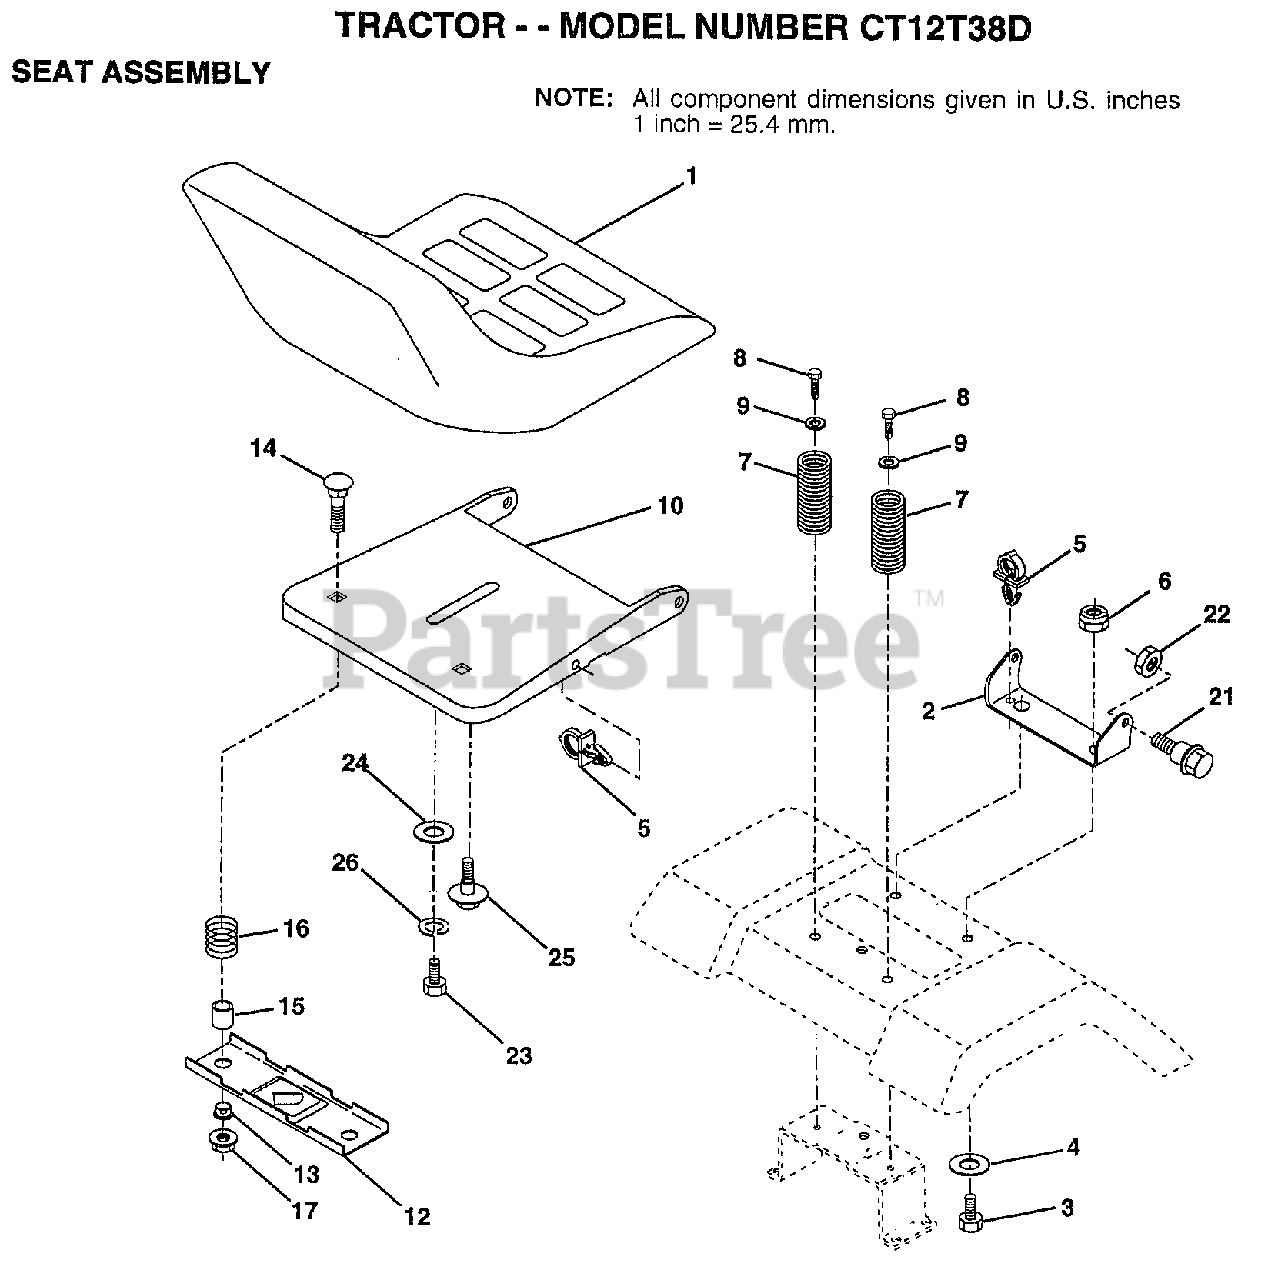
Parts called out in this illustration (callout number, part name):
2	BRACKET PVT SEAT
3	BOLT
4	WASHER PM
5	CLIP.PUSH-IN.HING
6	NUT
7	SPRING COMPRESSIO
8	SCREW GTV
9	WASHER
10	PAN-SEAT
12	BRKT SWITCH
13	BUSHING
14	BOLT-RD HD SQ NK
15	SPLIT SPACER
21	"BOLT,SHOULDER"
22	NUT
23	BOLT
24	WASHER
25	"BOLT,SHOULDER"
26	LOCKWASHER
